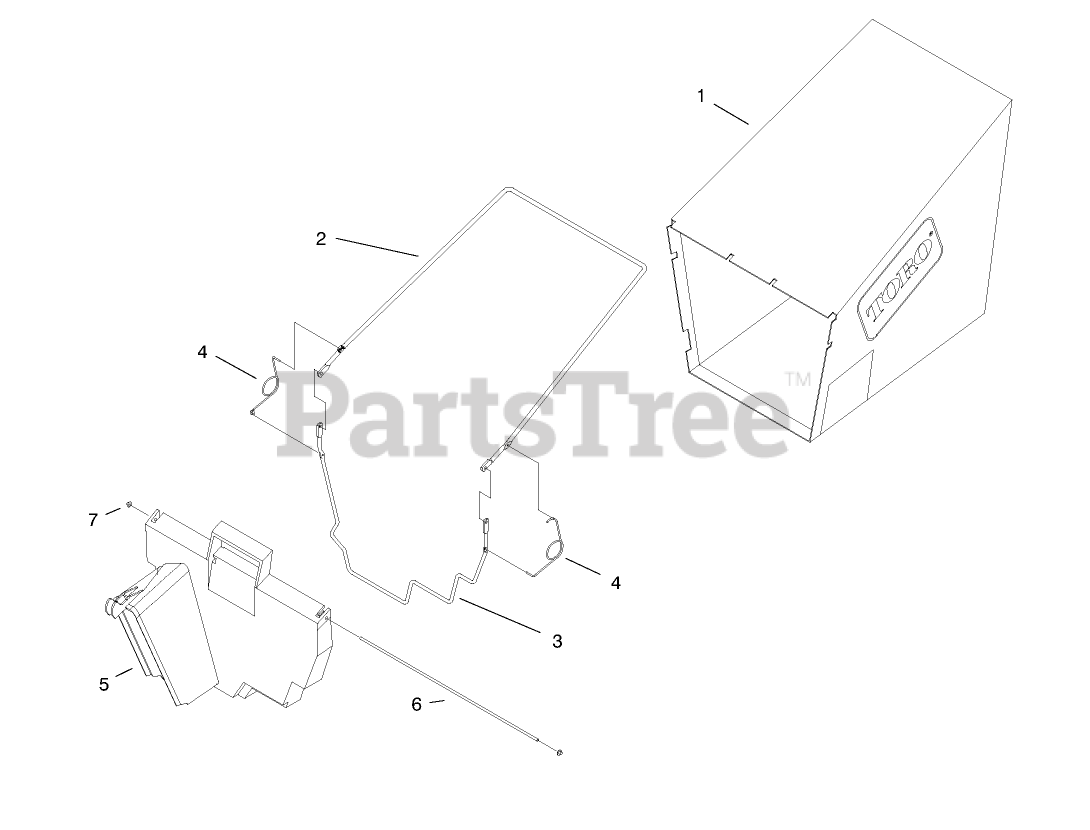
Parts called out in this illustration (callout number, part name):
1	BAG-GRASS
2	FRAME-UPPER BAG
3	FRAME-LOWER BAG
4	SPRING
5	DOOR-BAG
6	HINGE-BAG DOOR
7	NUT-PUSH
